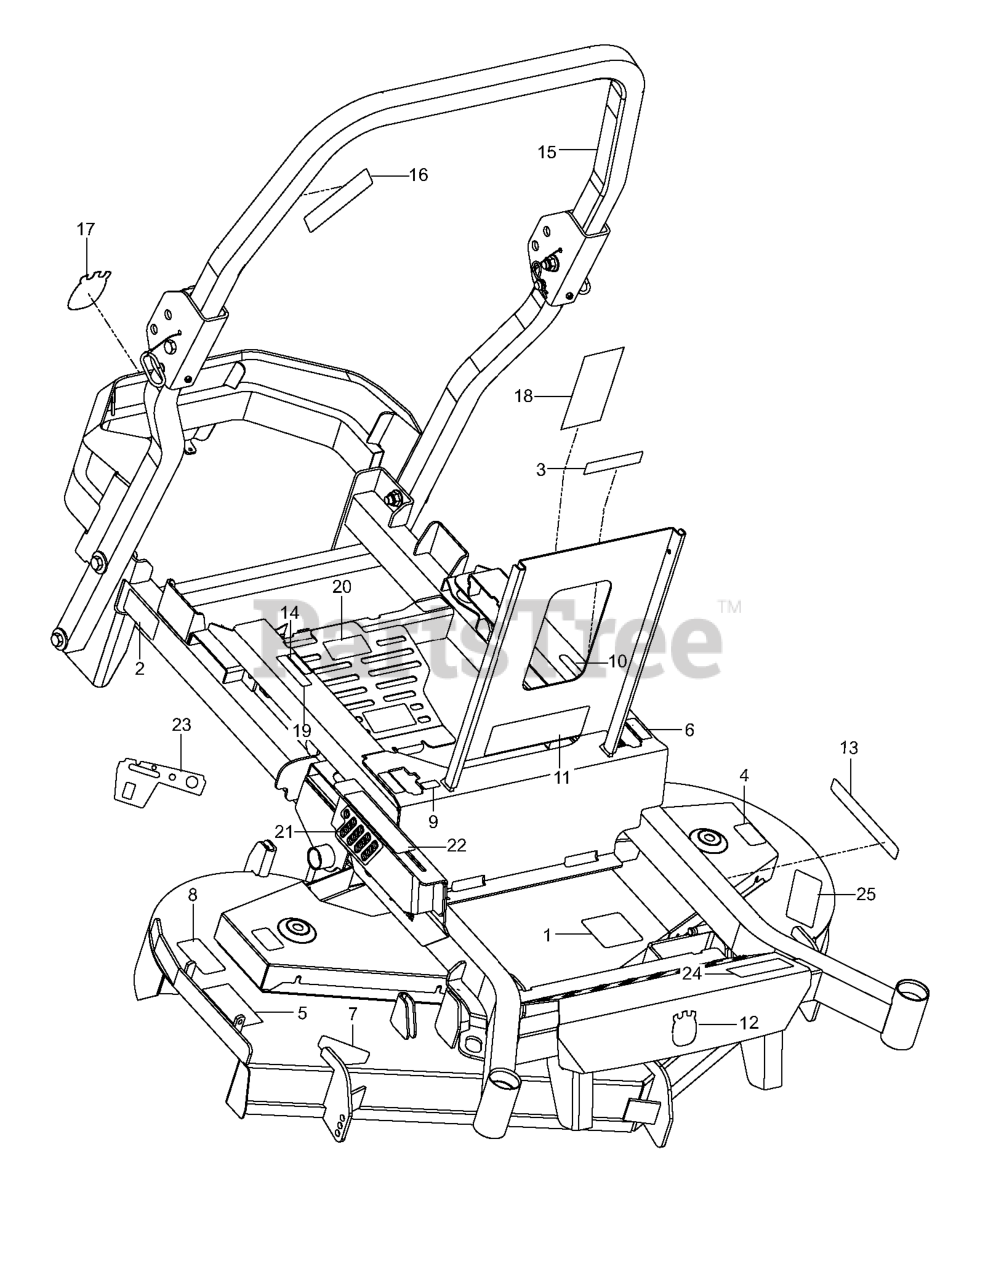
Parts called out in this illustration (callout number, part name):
1	DECAL, BELT ROUTING
2	DECAL, BELT DRIVE
3	EURO DECAL-BATTERY WARNIN6
4	DECAL.DECK.6MIL.EURO.NOSTEP
5	DECAL, EURO SEVERING
6	DECAL, MOTION CONTROL
7	DECAL, DECK DEFLECTOR, WARNING
8	DECAL.DECK.6MIL./DEF.SHLD.WARN
9	DECAL, F.S.T.
10	DECAL, PARK BRAKE
11	DECAL, WARNING
12	DECAL.AUGER.HUSQ.CROWN.SNOW
13	RP.DECAL.BADGE.170MM.TEXTLOGO
14	DECAL, FUSE
15	DECAL, ROPS
16	DECAL, ROPS, WARNING
17	DECAL, CROWN H, 110MM
18	DECAL, SERVICE
19	DECAL, WARNING SPARK ARRESTOR
20	HG_DECAL, ZT-3400
21	DECAL, HEIGHT
22	DECAL, RELEASE LEVER
23	DECAL.CONTROLPANEL.CHECKENGINE
24	DECAL.P-ZT60
25	ANTI-SKID PAD
